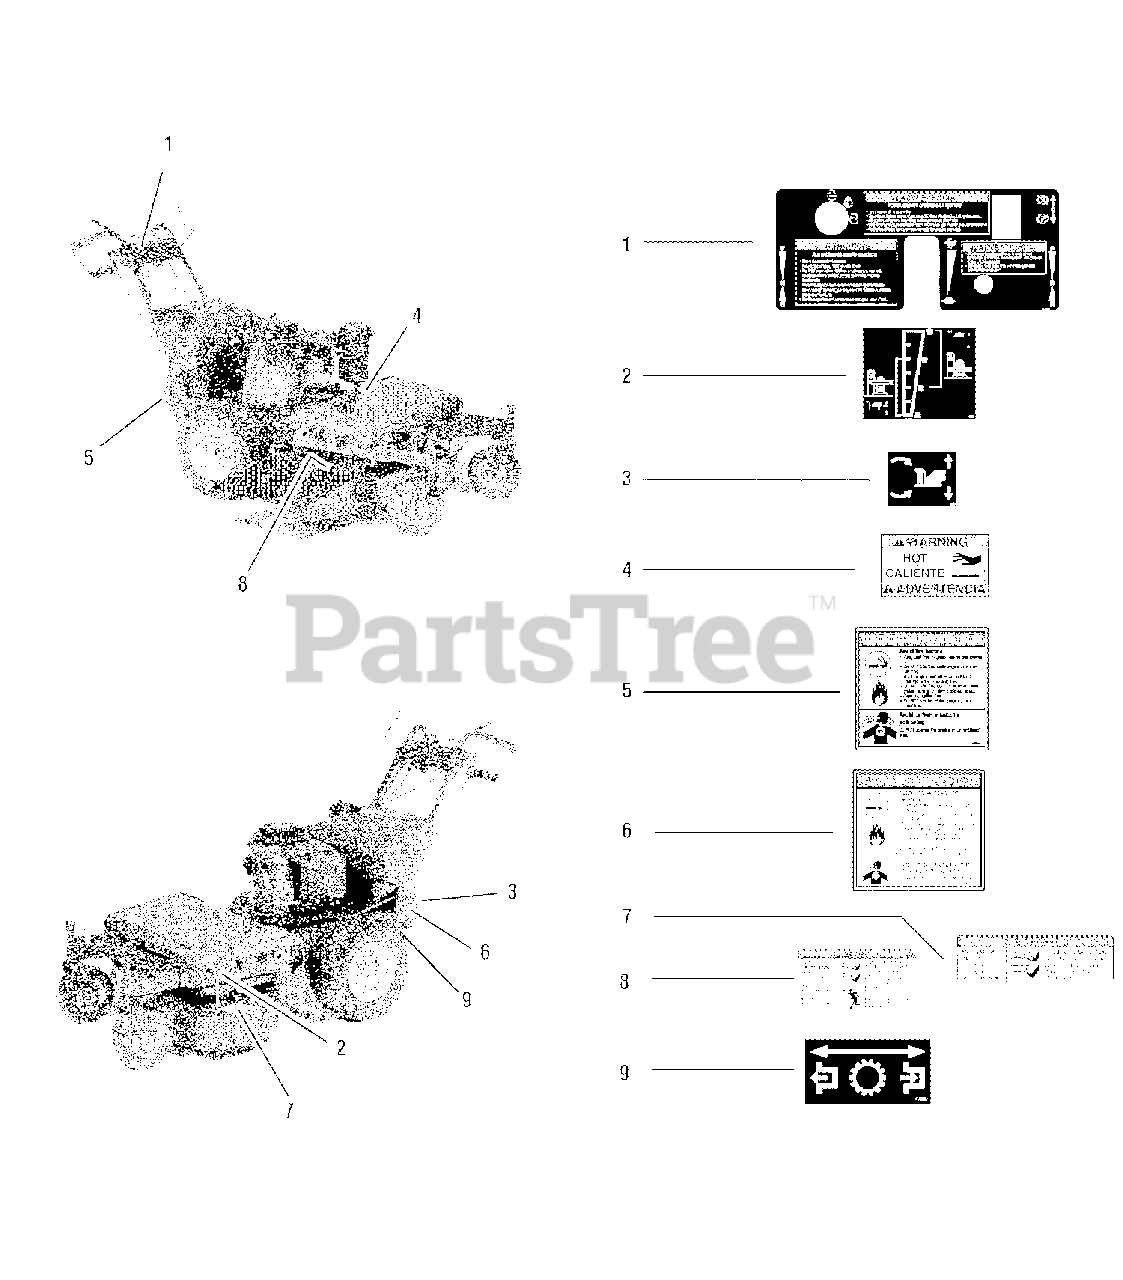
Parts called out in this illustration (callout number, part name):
1	DECAL, CONTROL PLANEL, HC
2	DECAL, HEIGHT OF CUT
3	DECAL, DECK HEIGHT ADJUST
4	DECAL, WARNING, HOT
5	DECAL, DANGER
6	DECAL, DANGER, FIRE (SP)
7	DECAL, DANGER, MOWER
8	DECAL, DANGER, MOWER DISCHARGE
9	DECAL, HYDRO RELEASE
